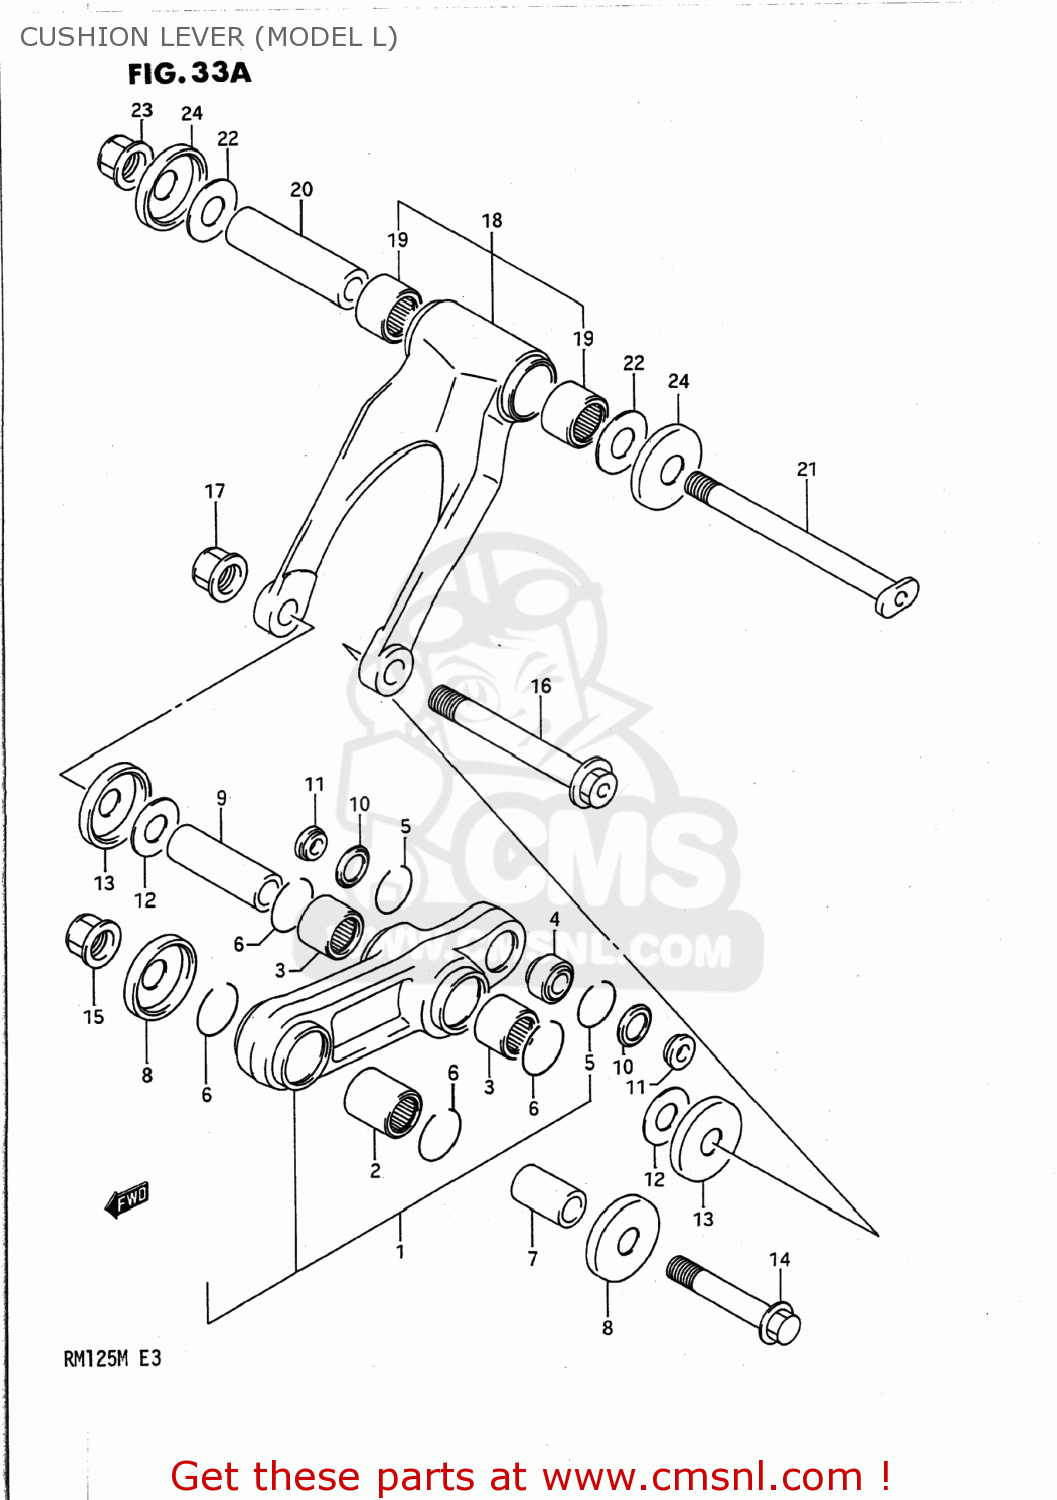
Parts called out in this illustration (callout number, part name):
1	LEVER SET,REAR CUSHION
2	BEARING(20X27X25)
3	BEARING
4	BEARING,RR CUSHION LEVER
5	RING
6	CIRCLIP
7	SPACER,RR CUSHION LEVER FR
8	SEAL,REAR CUSHION LEVER
9	SPACER,RR CUSHION LEVER CTR
10	SEAL,RR CUSHION LEVER RR DUST
11	SPACER,RR CUSHION LEVER RR
12	WASHER
13	SEAL,REAR CUSHION LEVER
14	BOLT,RR CUSHION LEVER FR
15	NUT 12MM
16	BOLT,REAR CUSHION LEVER,CENTER
17	NUT
18	ROD SET,RR CUSHION LEVER
19	BEARING(20X27X25)
20	SPACER,RR CUSHION ROD
21	BOLT,REAR CUSHION ROD
22	WASHER
23	NUT
24	SEAL,RR CUSHION LEVER
